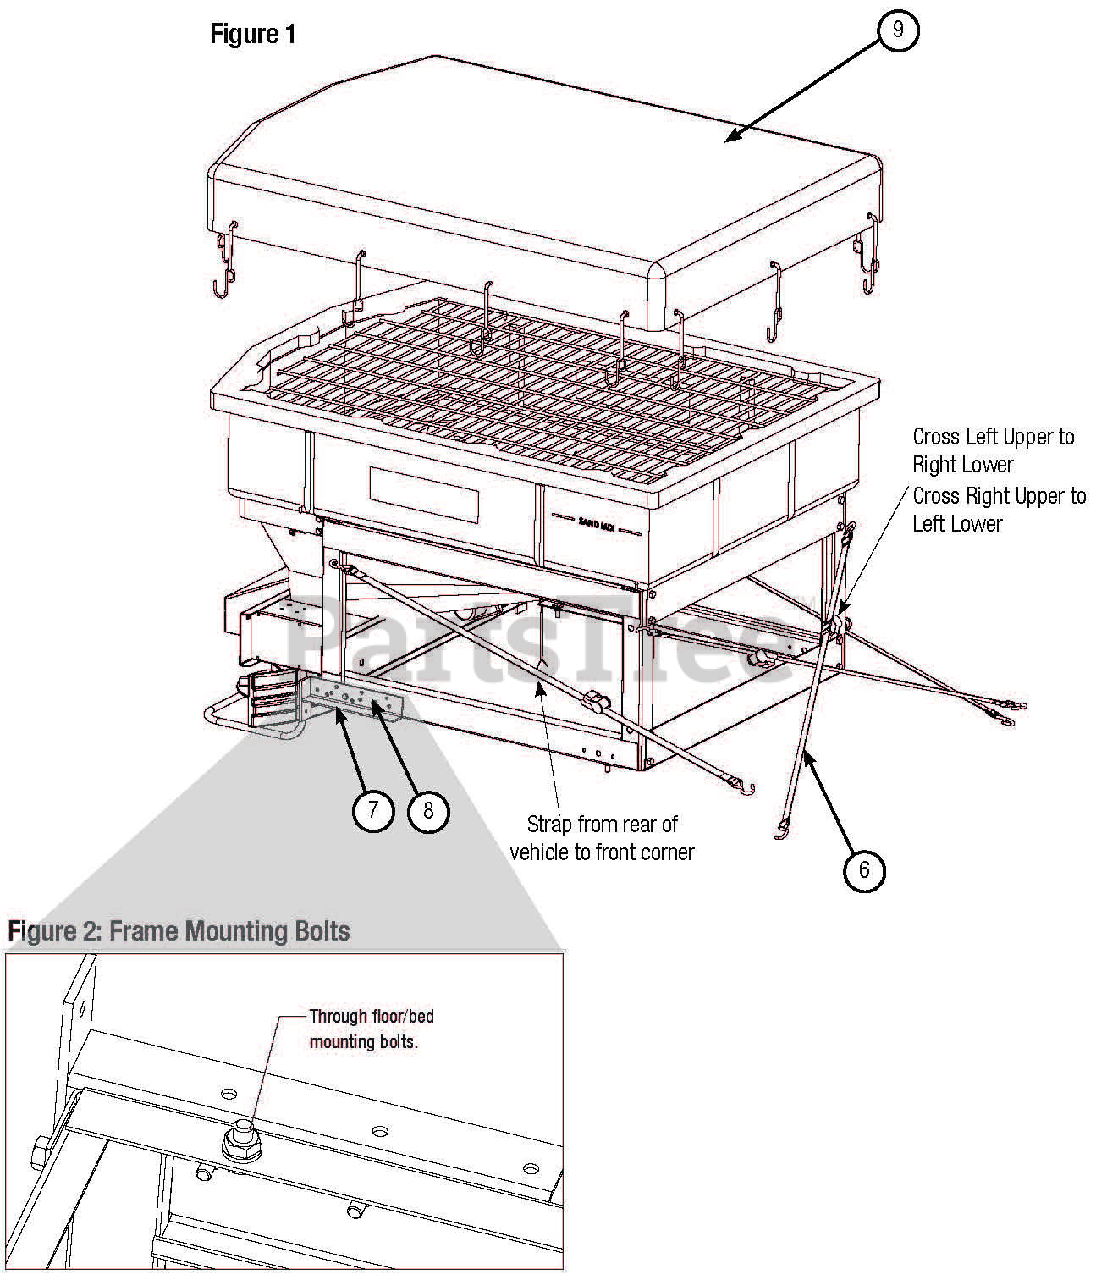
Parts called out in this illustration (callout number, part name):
6	Ratchet Strap
7	Adjustable Stop Bracket , Right
8	Adjustable Stop Bracket , Left
9	Tarp Kit , SP-3000 Tarp Kit
